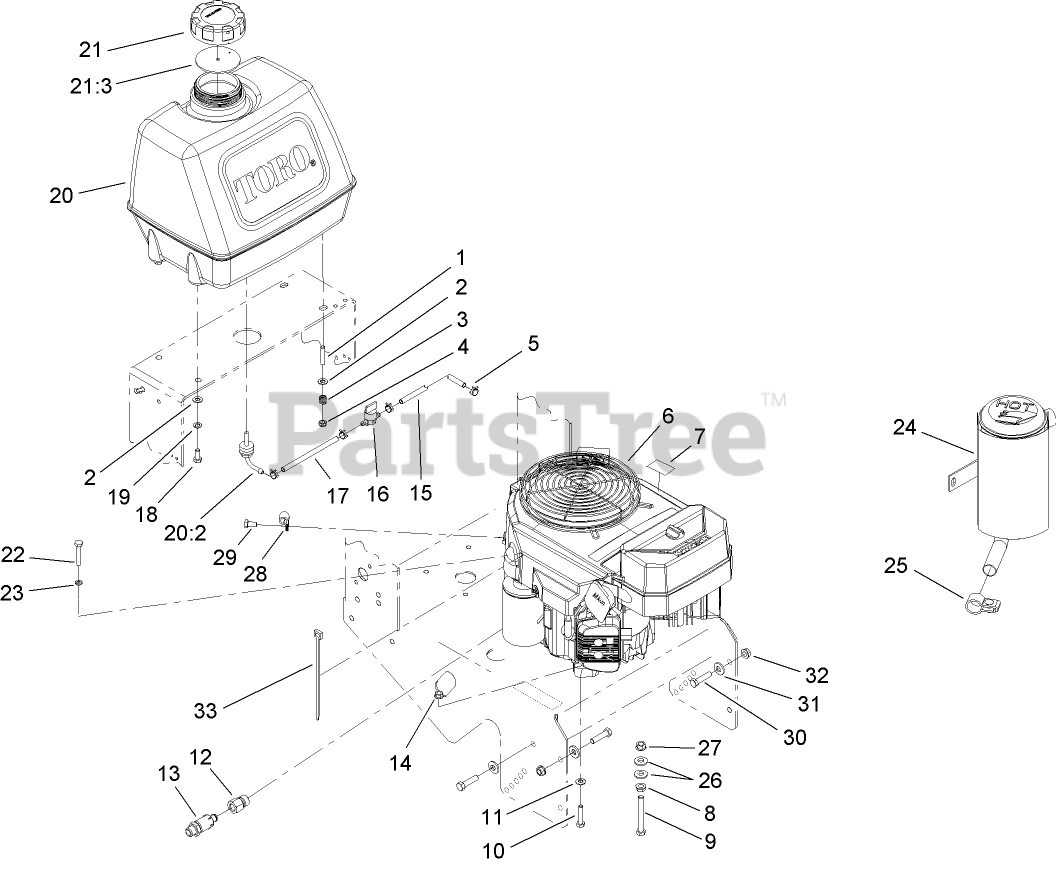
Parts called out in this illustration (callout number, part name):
2	WASHER-PLAIN
3	SPRING-TANK, FUEL
4	NUT-LOCK, NI
7	DECAL-WARNING
8	NUT-HHF, WHIZ
9	SCREW-HH
10	SCREW-HH
11	WASHER-SPRING
12	Adapter
13	VALVE-DRAIN, OIL
14	NUT-HF
15	HOSE-FUEL
16	VALVE-FUEL
17	HOSE-FUEL
18	SCREW-HH
19	WASHER-LOCK
20	FUEL TANK ASM
20:2	FITTING-FUEL, BULKHEAD
21	GAS CAP ASM
21:3	GASKET-CAP, GAS
22	SCREW-HH
23	WASHER-LOCK
24	MUFFLER
25	CLAMP-MUFFLER
26	WASHER-BELLEVILLE
27	NUT-HF
28	Clip-Loom
29	SCREW-HH
30	SCREW-HH
31	WASHER-BELLEVILLE
32	NUT-HHF, WHIZ
33	TIE-PLASTIC
